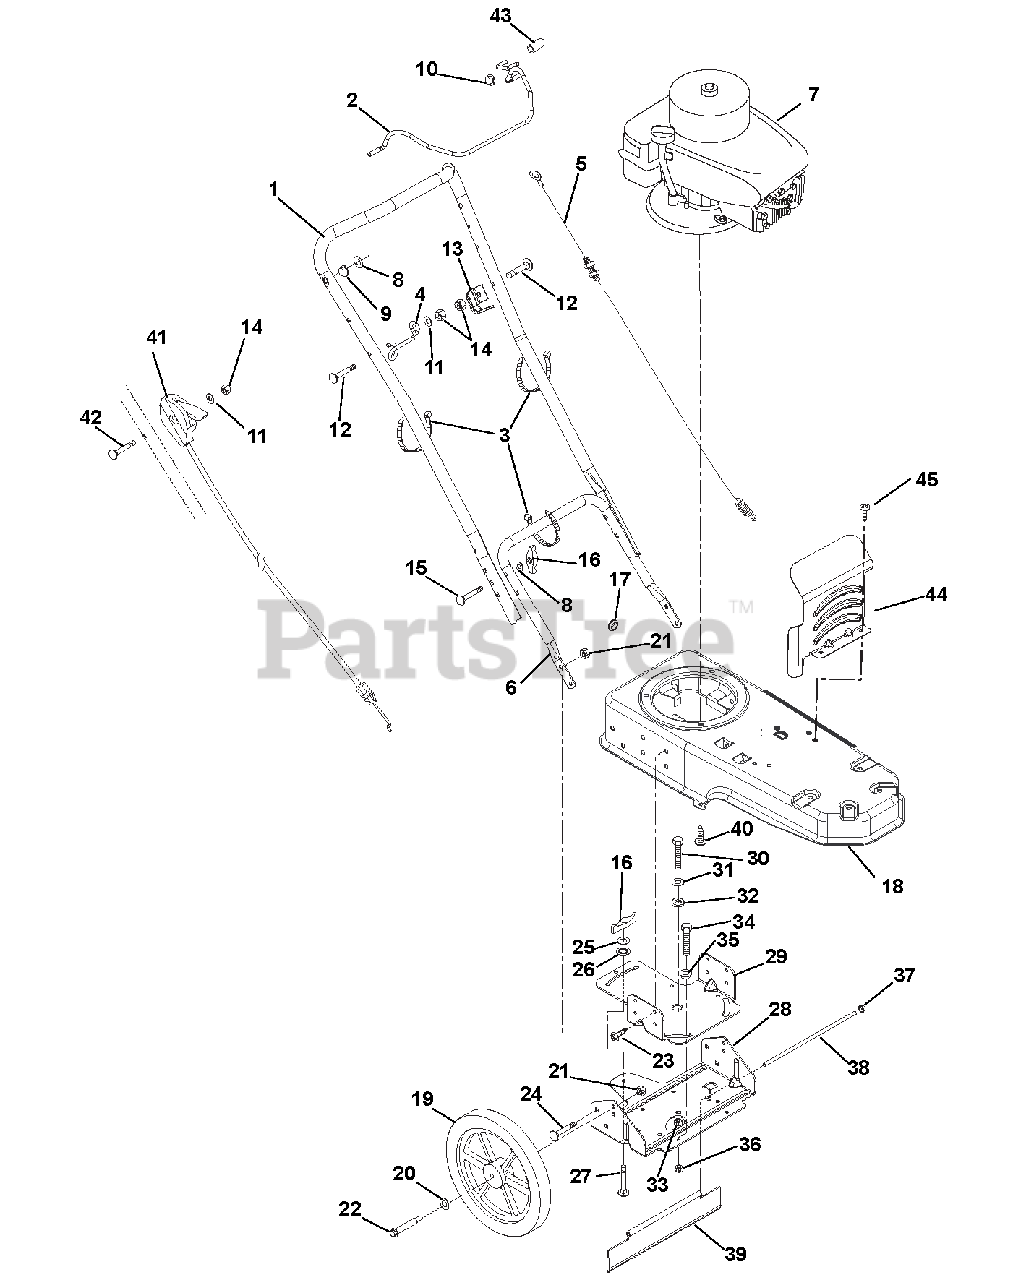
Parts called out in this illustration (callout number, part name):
1	HANDLEBAR - UPPER
2	BAIL SS LF
3	CABLE TIE LG 5-1/2
4	GUIDE - PULLCORD
5	CABLE - CONTROL
6	HANDLEBAR - LOWER
7	KIT - 6 HP TEC ENGINE-ARIENS
8	@WSHR-FL-STL.344X.688X.065YWZC
9	BSHG-FLG .325X.444X.440X.560
10	PUSH NUT, .25
11	@WSHR-FL-STL.281X.62X.065 YWZC
12	BLT-RDHDXLSQNK.25-20X1.25 G5ZC
13	ANCHOR - CABLE
14	@NUT-LK-CTR .25-20 YWZC
15	BLT-RDHDSQNKFT .31-18X2.0 G5YZ
16	KNOB - WING .312-18 UNC
17	GROMMET .50 ID
18	FRAME - TRIMMER
19	WHEEL 14 X 1.75 X .50
20	WSHR-FL-STL .52X.827X.062 YWZC
21	@NUT-LK-CTR .38-16 YWZC
22	BLT-SHLDR .38-16X2.50 HWH G5
23	@SCR-TAP .38-16X.75 HWH TR YWZ
24	@BLT-RDHDSQNK .38-16X.75 G5YZ
25	@WSHR-FL-STL.38X.875X.083 YWZC
26	NUT-PUSH .312
27	@BLT-RDHDSQNK .31-18X1.00 G5YZ
28	BRACKET - AXLE - SWIVEL
29	BASE - SWIVEL
30	@BLT-HEX .50-13X1.00 GR5 YWZC
31	@WSHR-FL-STL.563X1.38X.109YWZC
32	SPACER .531 X 1.00 X .225
33	@NUT-LK-CTR .50-13 YWZC
34	@BLT-HEX .31-18X1.00 GR5 YWZC
35	BSHG-FLG .32X.500X.344X.880
36	@NUT-LK-CTR .31-18 YWZC
37	NUT-PUSH .312 DIA. PAL
39	GUARD - REAR - SWIVEL
40	@SCR-TAP .38-16X1.00 HWH TR YZ
41	CONTROL - THROTTLE
42	BLT-RDHDXLSQNK .25-20X2.0 G5YZ
43	CAP, VINYL, .25 ID
44	GUARD - ENGINE
45	@SCR-TAP .38-16X.50 HWH TR YWZ
